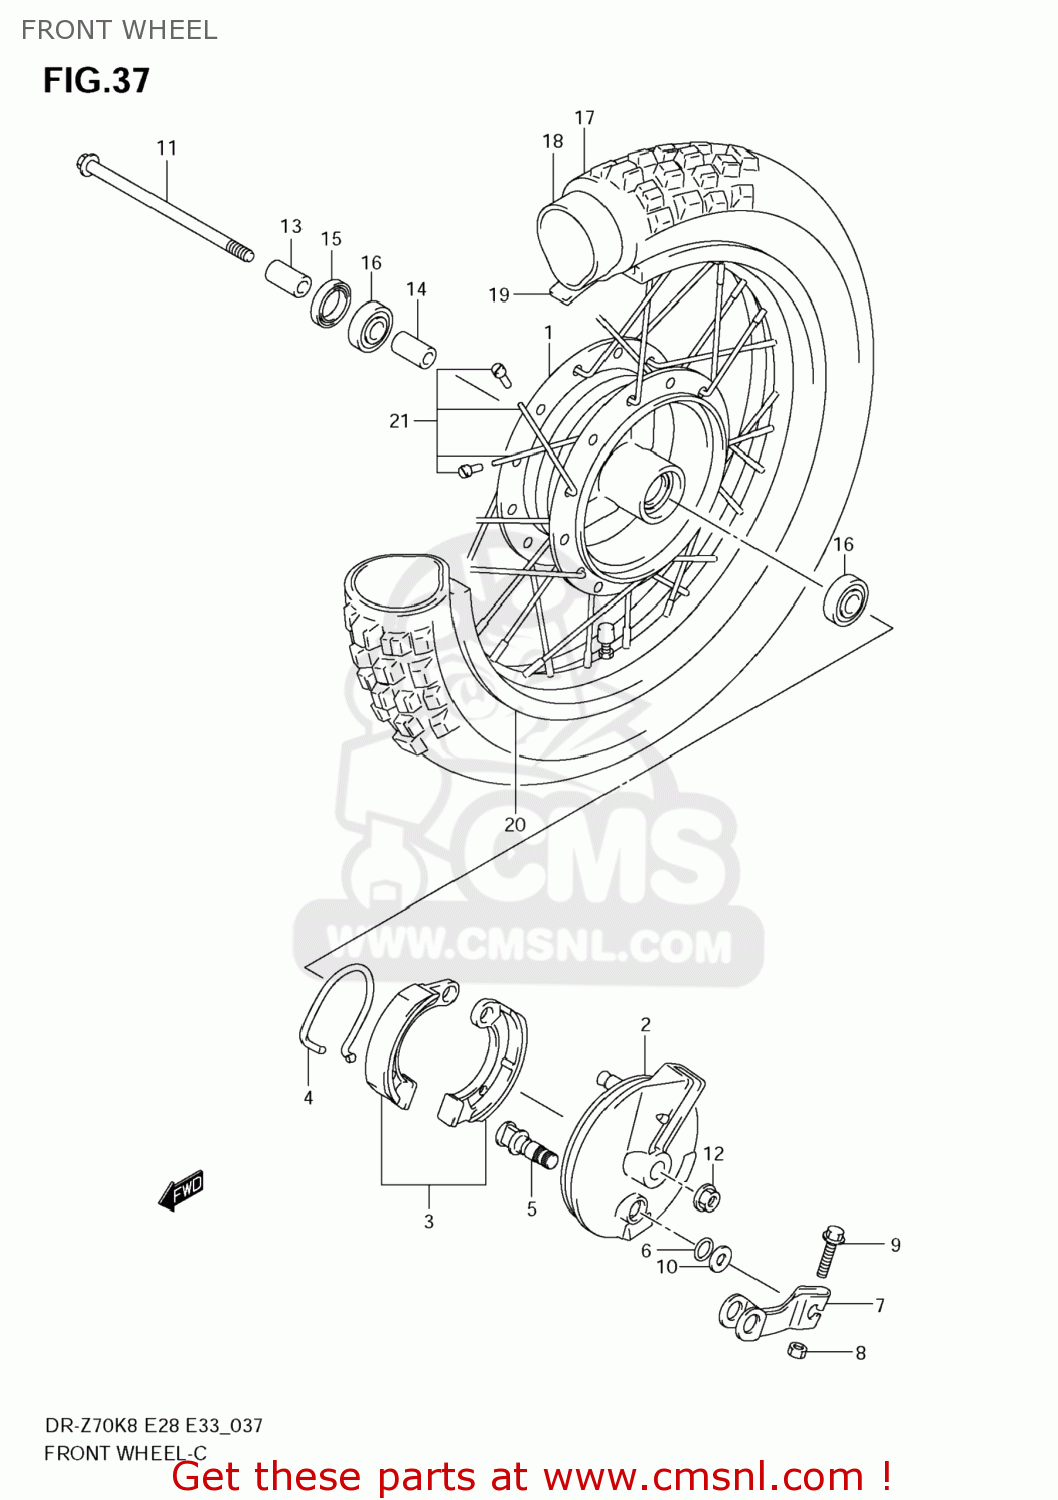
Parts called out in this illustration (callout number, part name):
1	HUB,FR WHEEL
2	PANEL,FR BRAKE ANCHOR
3	SHOE SET,BRAKE (NAS)
4	SPRING,BRAKE SHOE
5	CAM,BRAKE
6	O RING(D:2.4,ID:9.8)
7	LEVER,BRAKE CAM
8	NUT
9	BOLT
10	WASHER(10.5X18X1)
11	AXLE,FR
12	NUT
13	SPACER,FR AXLE,R
14	SPACER,FR HUB BEARING
15	SEAL,OIL(32X20X5)
16	BEARING (12X32X10)
17	TIRE(2.50 10)
18	TUBE ASSY,WHEEL INNER
19	PROTECTOR,WHL INR TUBE
20	RIM,WHEEL(10X1.40)
21	SPOKE SET,WHEEL
